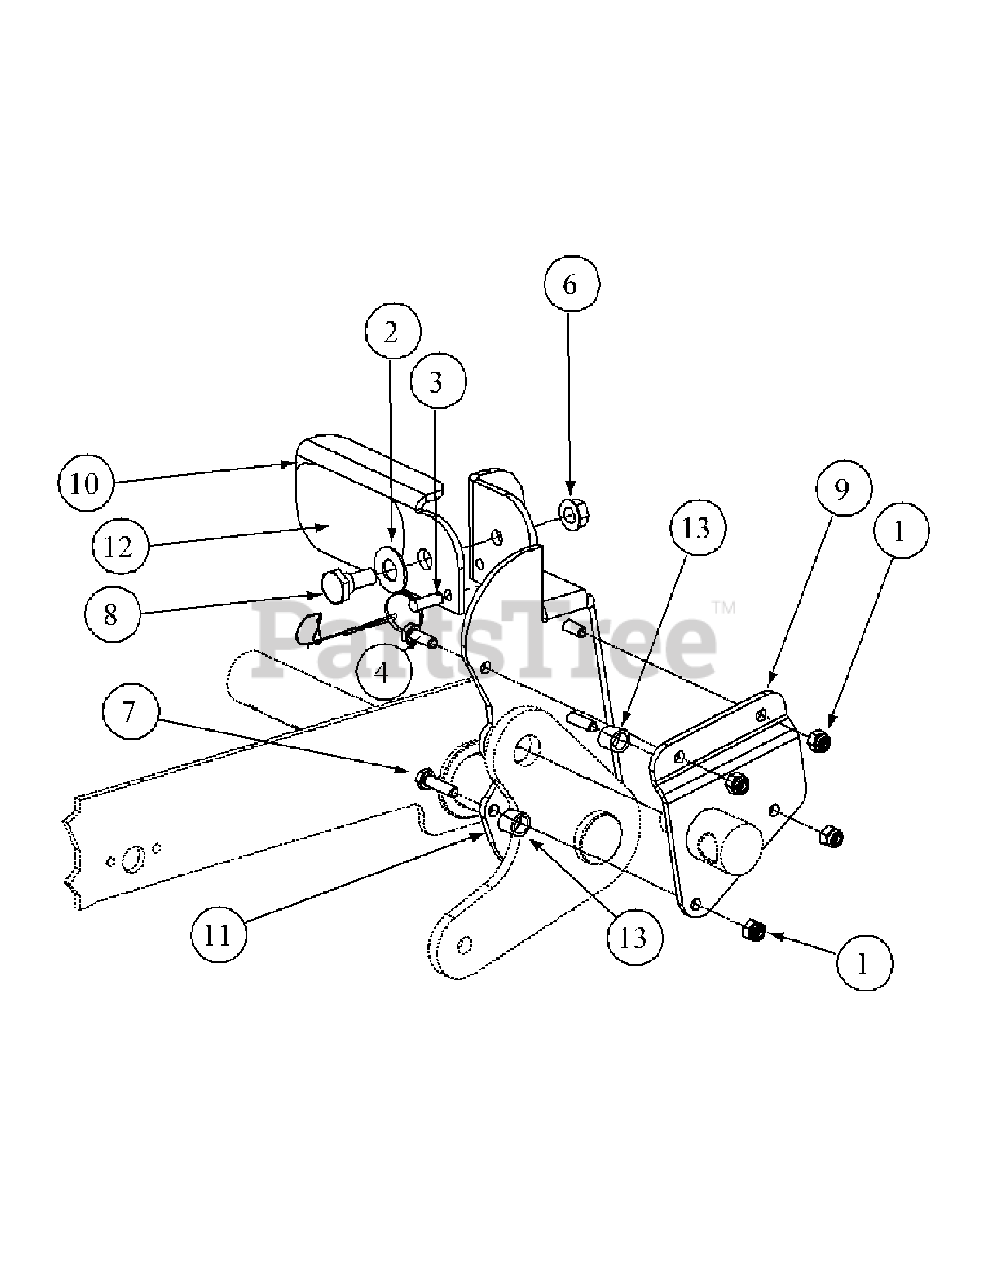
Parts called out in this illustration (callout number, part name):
1	Lock Nut, Nylon Insert, 1/4-20
2	Washer, 1/2 x 1 Shim
3	Detent Pin w/Lanyard, 1/4"
4	Hex Cap Screw, 1/4-20, .75
6	Hex Nut, Flange Lock 3/8-16
7	Hex Cap Screw, 1/4-20, 1.00
8	Shoulder Screw, .50x.27 Lg., 3/8-16
9	Foot Lift Backup Pedal
10	Deck Foot Pedal Lift
11	Deck Foot Pedal Lift Holder
12	Deck Foot Lift Pad
13	Turnbuckle Sleeve
